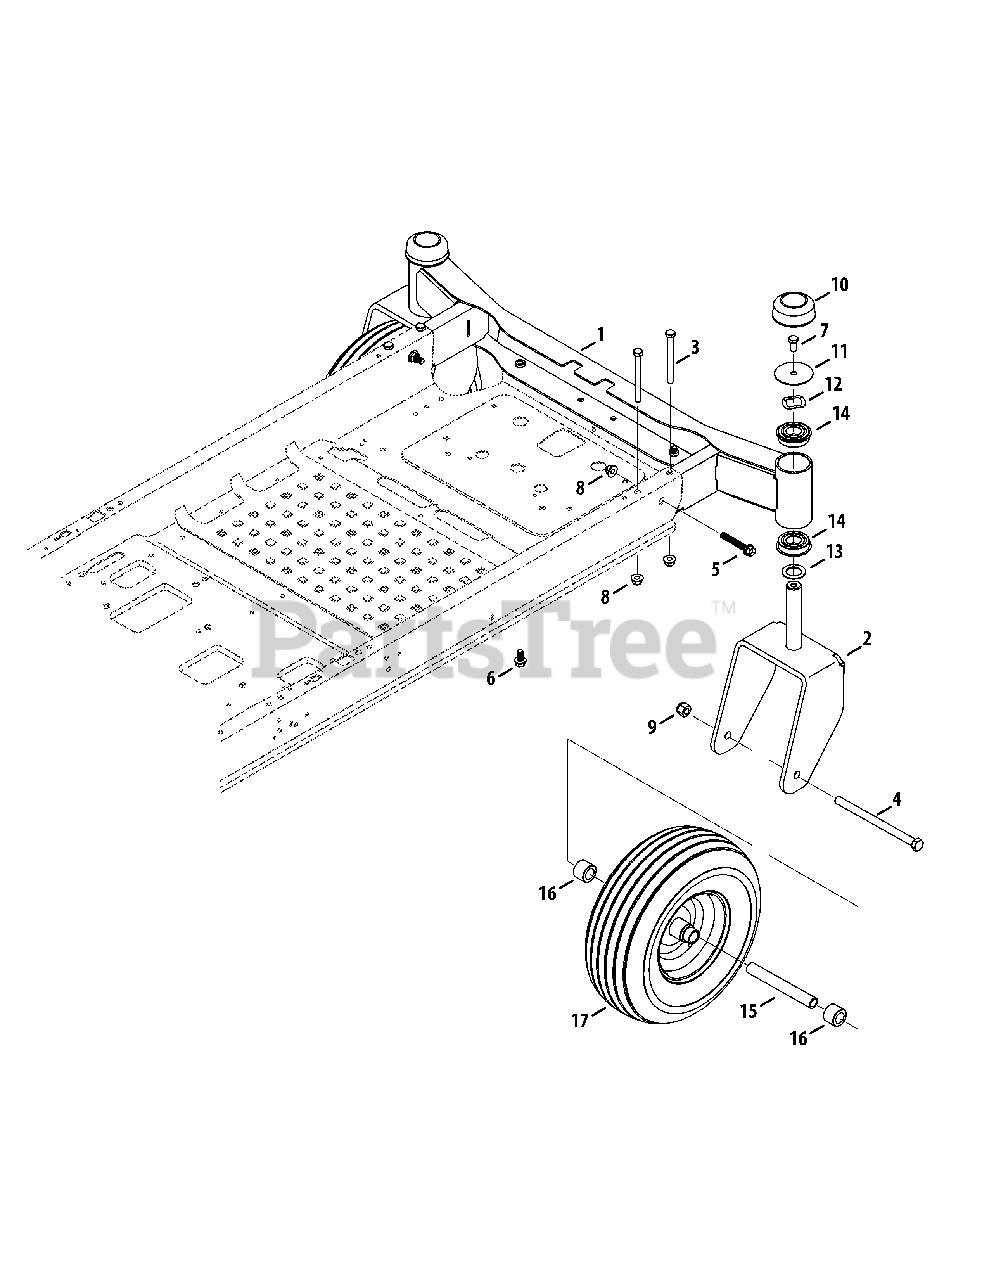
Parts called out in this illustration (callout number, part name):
1	Front Axle
2	Caster Wheel Bracket
3	Hex Cap Screw 3/8-16 x 3.75
4	Hex Cap Screw 1/2-20 x 7.25
5	Hex Flange Screw 3/8-16 x 2.00
6	Screw TT 3/8-16 x .750
7	Hex Cap Screw 3/8-16 x .750
8	Flange Lock Nut 3/8-16
9	Hex Lock Nut 1/2-20
11	Shoulder Spacer 2.50 x .02
12	Wave Washer 1.25 x 1.00 x .300
13	Flat Washer 1.010 x 1.56 x .060
14	Ball Bearing
15	Spacer .51 x .75 x 5.825
16	Hub .76 x 1.23 x .92
17	Wheel Assembly 13 x 5 x 6 (Grey)
